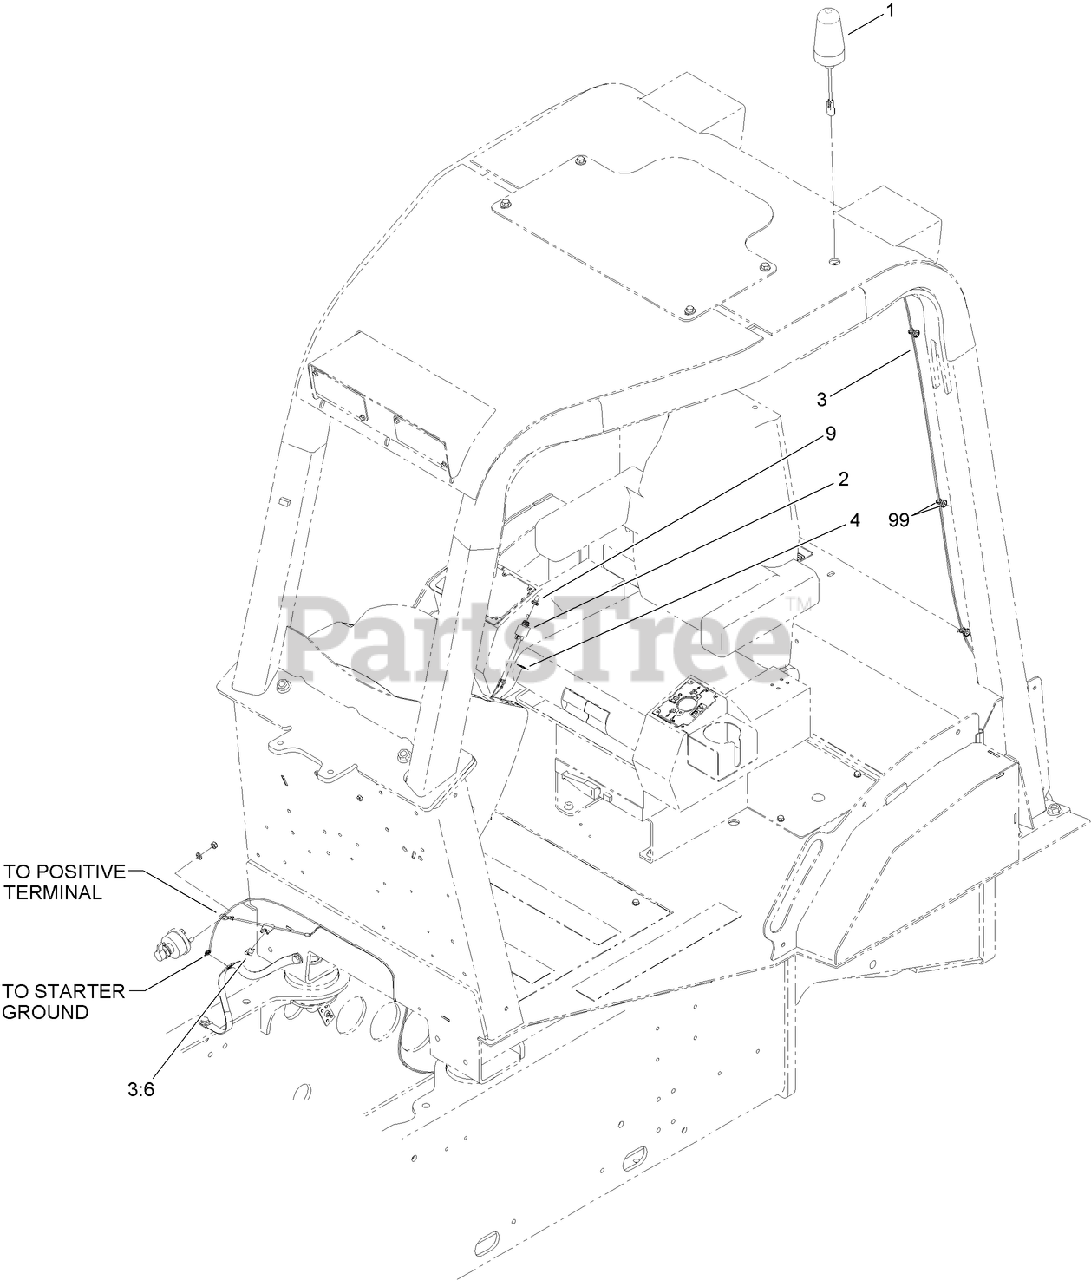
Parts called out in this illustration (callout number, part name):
1	LIGHT-STROBE
2	SWITCH
3	HARNESS-BEACON
3:6	FUSE-BLADE, 10 AMP
4	DECAL-BEACON
9	BOOT-TOGGLE SWITCH
99	MOUNT-TIE WRAP, MAGNETIC
99	TIE-CABLE
